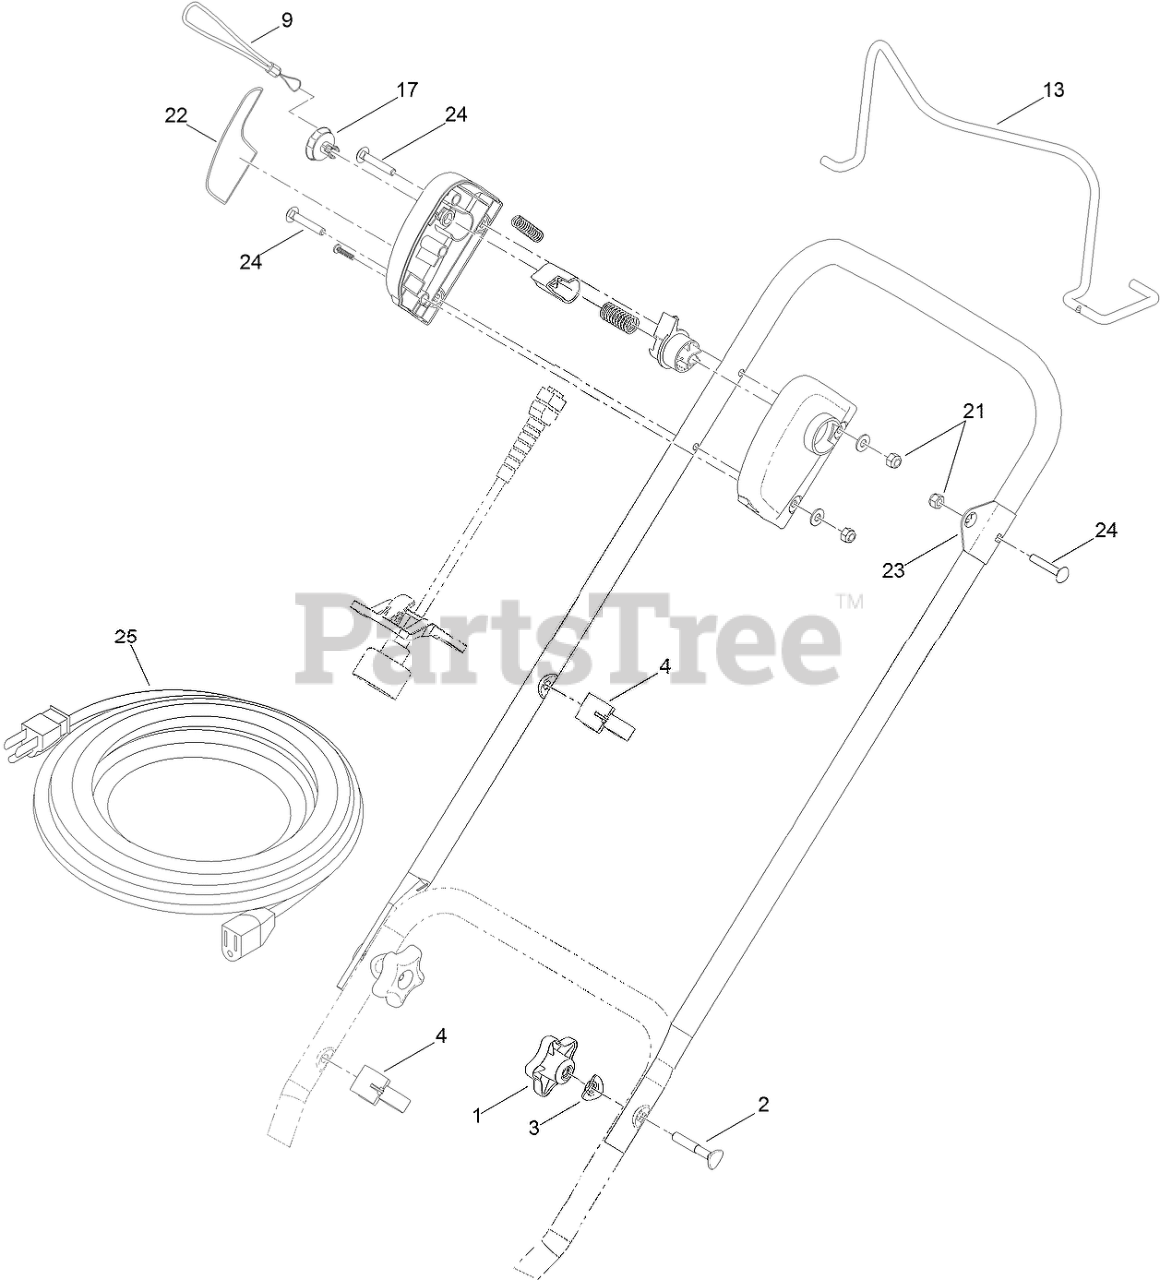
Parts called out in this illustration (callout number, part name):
1	KNOB-HANDLE
2	SCREW-HANDLE
3	WASHER
4	GUIDE-CABLE
9	CORD-KEY
17	KEY-BAIL
21	NUT-LOCK, NI
22	DECAL-OPERATION
23	BRACKET-BAIL
24	SCREW-CARR
25	CORD-EXTENSION, COLD WEATHER
